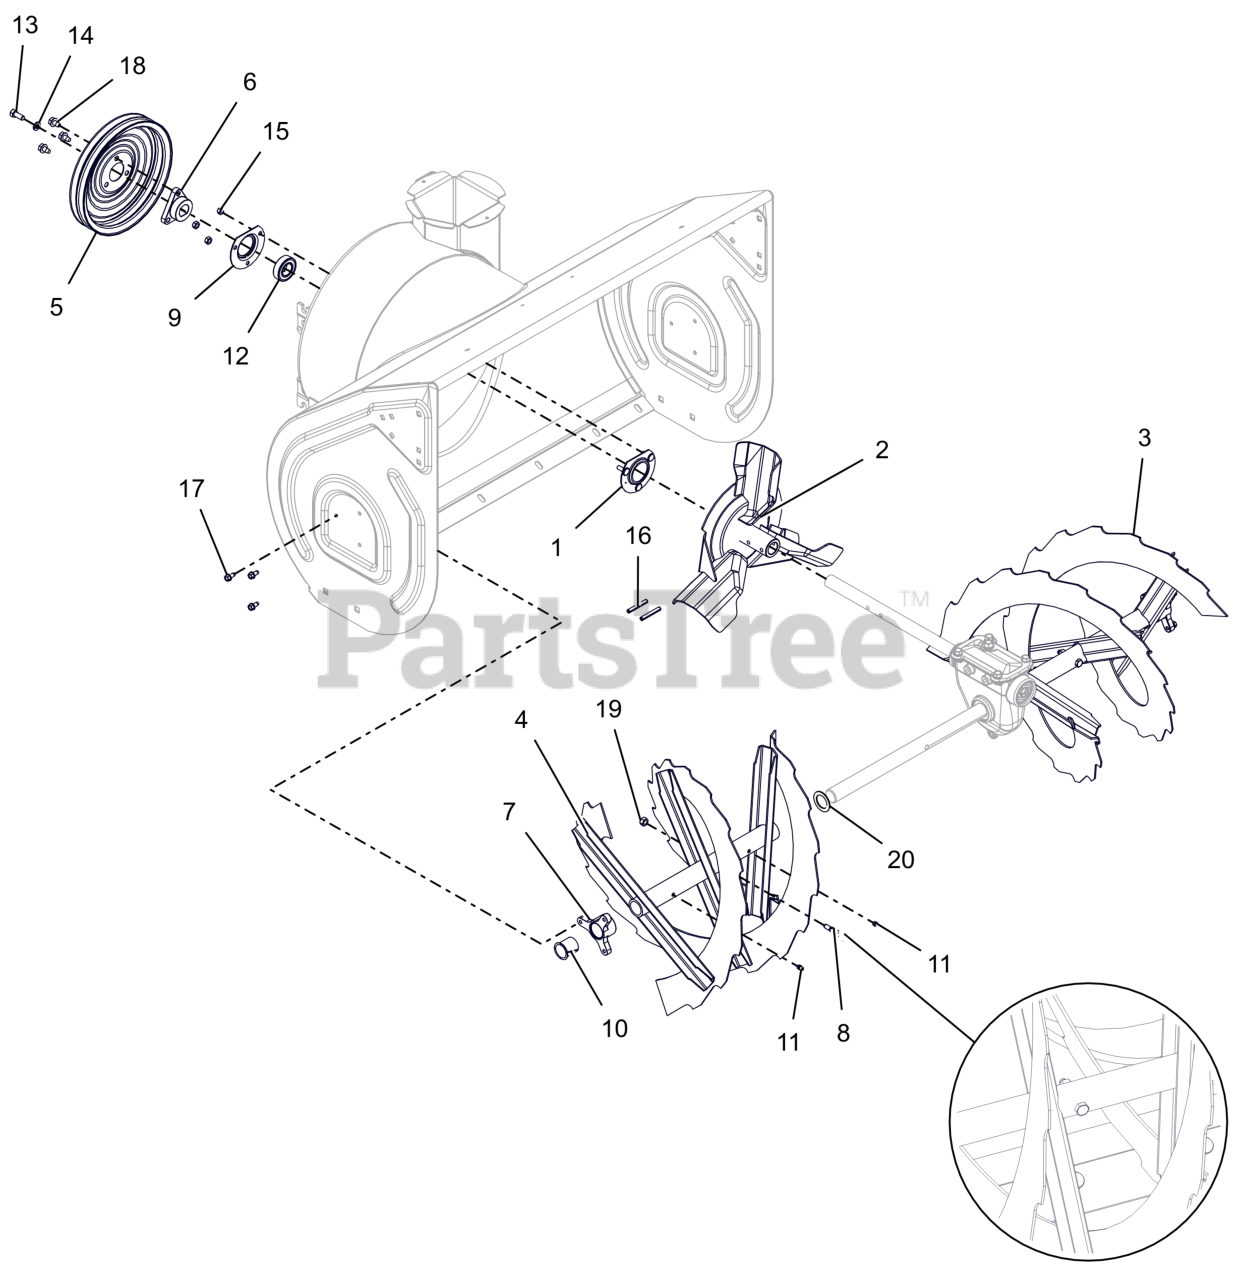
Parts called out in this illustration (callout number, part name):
1	BEARING FLANGE
2	IMPELLER, 3 BLADE-14"
3	RAKE, LH-32"(1 ID X 15.75 OD)
4	RAKE, RH-32"(1 ID X 15.75 OD)
5	PULLEY, SPIN FORM DUAL GROOVE
6	PULLEY HUB, D-BORE .87 PRO
7	BUSHING, RAKE SHAFT 1"
8	SHEAR BOLT SERVICE ASSEMBLY
9	BEARING FLANGE
10	BSHG-FLG SPLIT NYLINER 1.0" HP
11	ZERK,FITTING .25X.125 DRIVE IN
12	BRG-BALL .876X1.75X.50 RSTFP
13	BLT, HEX .31-24X.750 G5 ZCC
14	WSHR, LK-HVY .312X.097 ZCC
15	NUT,LK-CTR .25-20 GA ZCC
16	PIN-ROLL .250X1.75
17	SCR-TAP .25-20X.50 HWH ZCC
18	SCR,TAP .312-18X.50 HWH TR ZCC
19	NUT,LK-CTR .31-18 GA ZCC
20	WSHR, FLT 1.010X1.505X.062 ZCC
